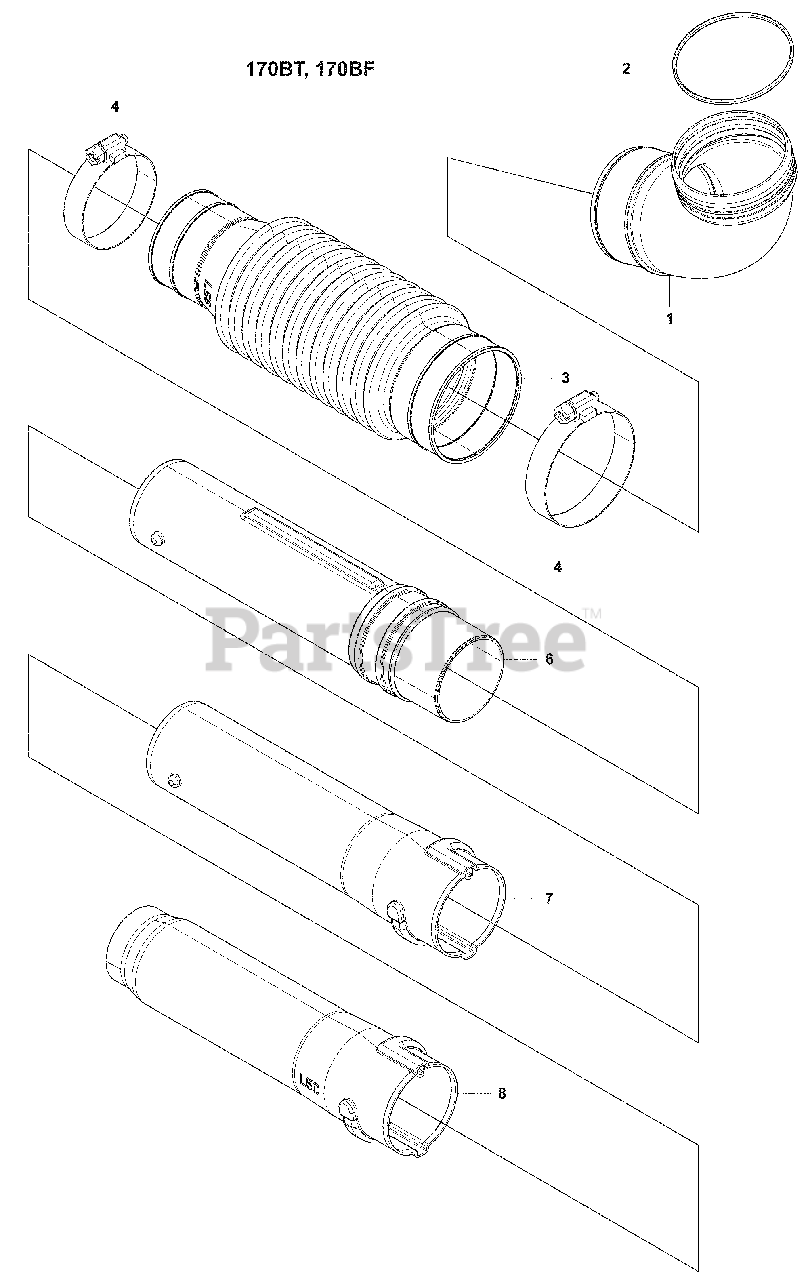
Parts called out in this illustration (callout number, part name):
1	Elbow
2	O-Ring
3	Flex Pipe
4	Clamp, F115
5	Clamp, F96
6	Swivel Joint
7	Pipe
8	Pipe, End
